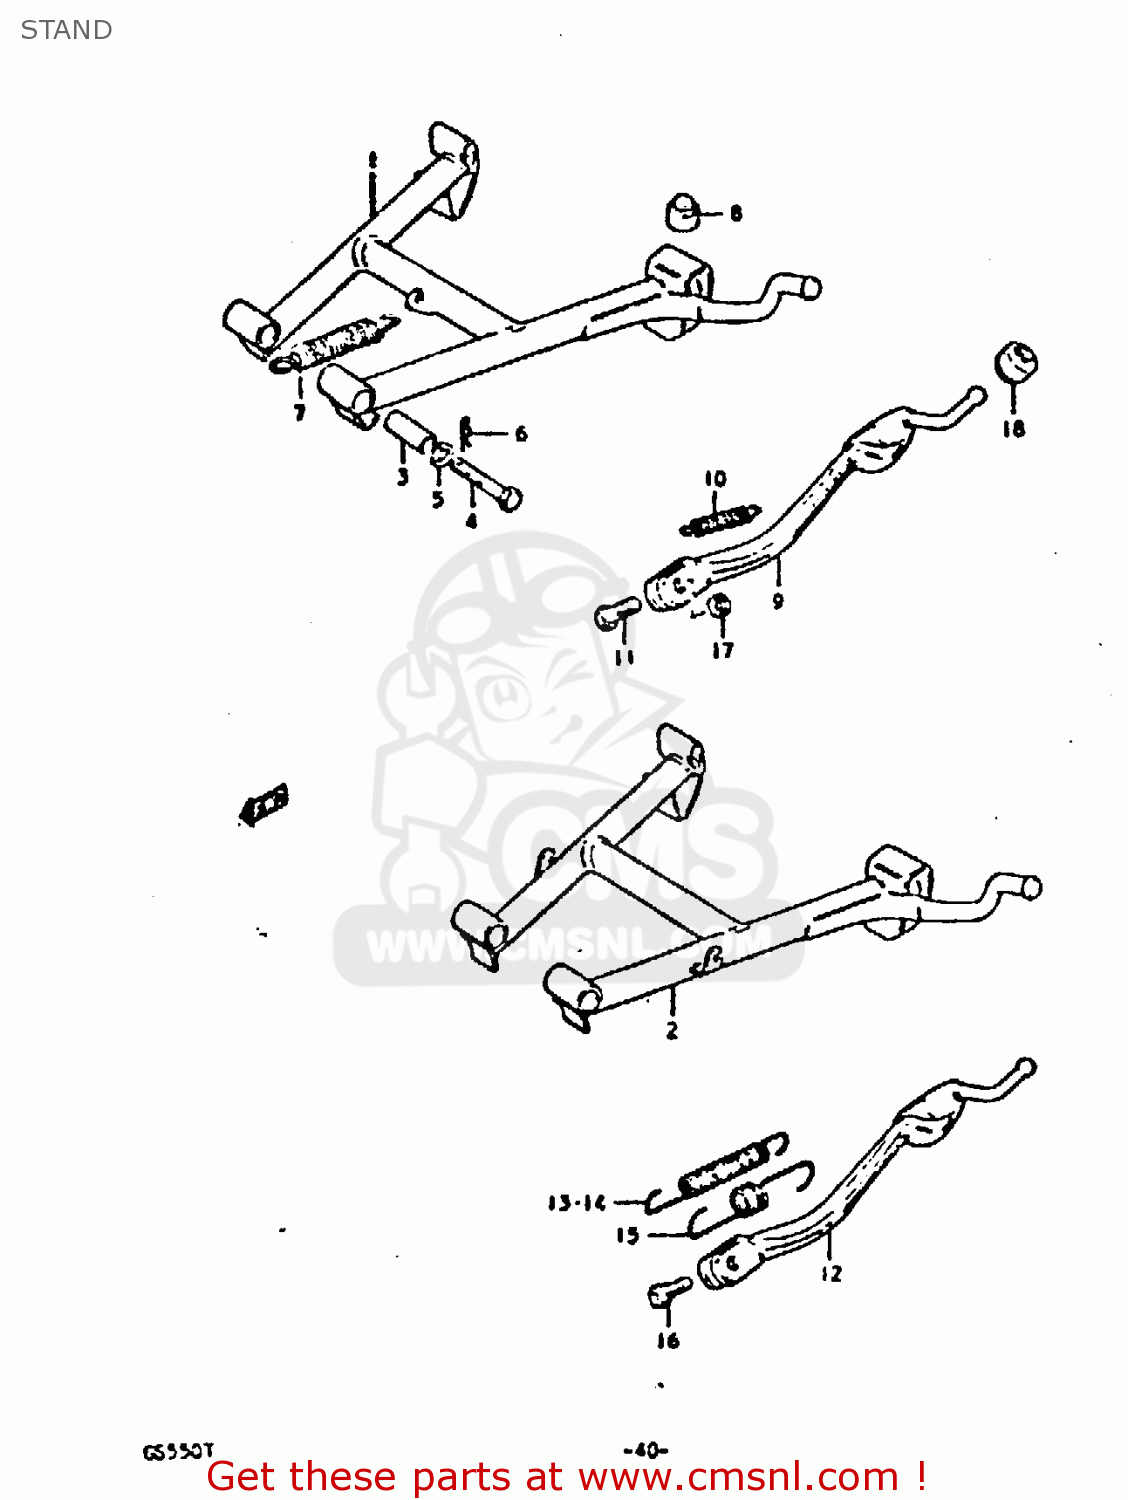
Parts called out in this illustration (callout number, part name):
1	STAND,CENTER
3	SPACER(10X16X38.8)
4	BOLT
5	LOCK WASHER
6	CLIP
7	SPRING
8	CUSHION
9	STAND,SIDE
10	SPRING
11	BOLT(10X30)
17	NUT
18	CUSHION
